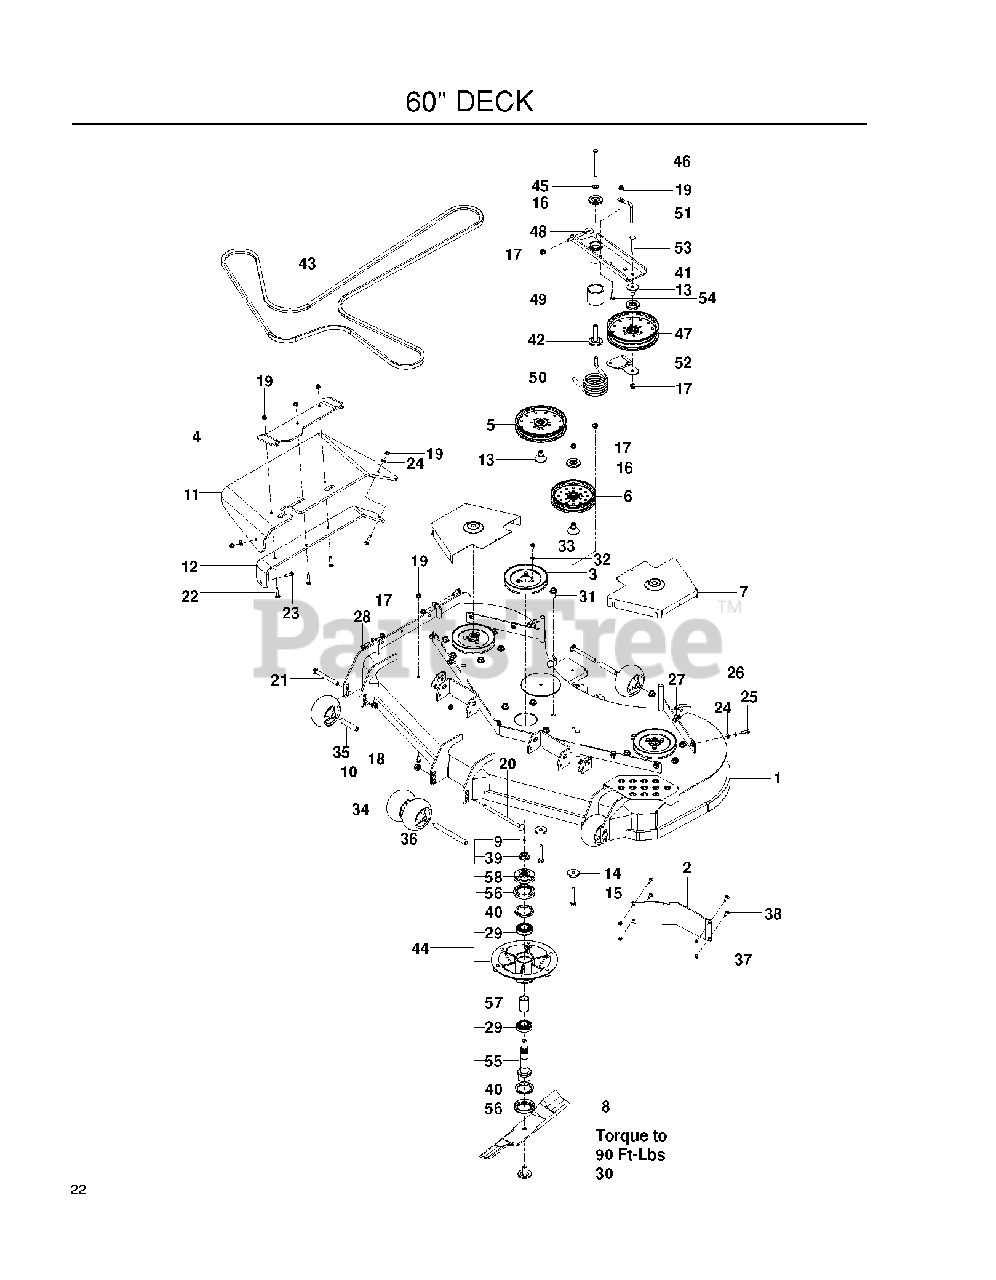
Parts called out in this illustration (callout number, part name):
1	DECK.FAB.W/DECALS.60.BLUE.DIXO
2	BAFFLE, DIVERTER 54"/60" LH
3	PULLEY - 6.57
4	BRKT - CHUTE MTG BLACK
5	PULLEY - 7" NARROW
6	PULLEY IDLER, 6" NARROW
7	SHIELD, BELT, 60" BLUE
8	BLADE - HEAVY DUTY 21"
9	ZERK
10	NUT, 1/2-13 HEX FLG NYLOC ZD
11	CHUTE, DISCHARGE 48-52
12	BRKT, CHUTE SUPPORT BLACK
13	BEARING, IDLER ARM
14	SPINDLE WASHER
15	HHFS 3/8-16 X 2 3/4
16	DUST SHIELD
17	NUT 3/8-16 HEX FLG NYLOC ZD
18	HHFS 5/16-18 X 3/4
19	5/16-18 NYLOC FLANGE NUT
21	RHSNB 1/2-13 X 4.75 GR5 ZD
22	RHSNB 5/16-18 X 1-1/2 GR 5 ZD
23	BOLT, CARRIAGE 5/16X1-1/4
24	WASHER 5/16 FLAT
25	HCS 5/16C X 1
26	WASHER 5/16 LOCK
27	U-CLIP 5/16-18 NUT RETAINER
28	HHFS 3/8-16 X 1 GRD 5 ZD
29	BEARING - 206KRR8
30	BLADE BOLT/WASHER
31	HHFS 1/2-13 X 1 GR5 ZD
32	WASH 5/16 DISC SPRING ZD
33	HCS 5/16-18 X 1/2 GR 5 ZD
34	ROLLER, GAUGE .635 BORN
35	TUBE, ROLLER AXLE
36	TUBE, ROLLER AXLE LONG
37	NUT 1/4-20 NYLOC
38	RHSNB, 1/4-20 X 1, GR5
39	NUT FLANGE 3/4-16
40	V-RING, 55MM
41	Idler Arm Assembly, PZ
42	BEARING, IDLER PIVOT
43	BELT, "B", 176
44	SPINDLE ASM. 10"
45	WASHER, 3/8 THICK
46	HCS 3/8-16 X 4-1/2 GR 8 ZD
47	PULLEY - IDLER 7"
48	Eyebolt, 3/8 X 4"
49	Idler Pivot Spacer
50	SPRING, TORSION, IDLER
51	Belt Keeper
52	BELT.GUIDE.BLACK
53	CARRIAGE BOLT 3/8-16 X
54	RHSSNB 5/16C X 1.0
55	SHAFT - SPINDLE
56	CUP - DEBRIS
57	SPACER - BEARING
58	HUB - PULLEY
